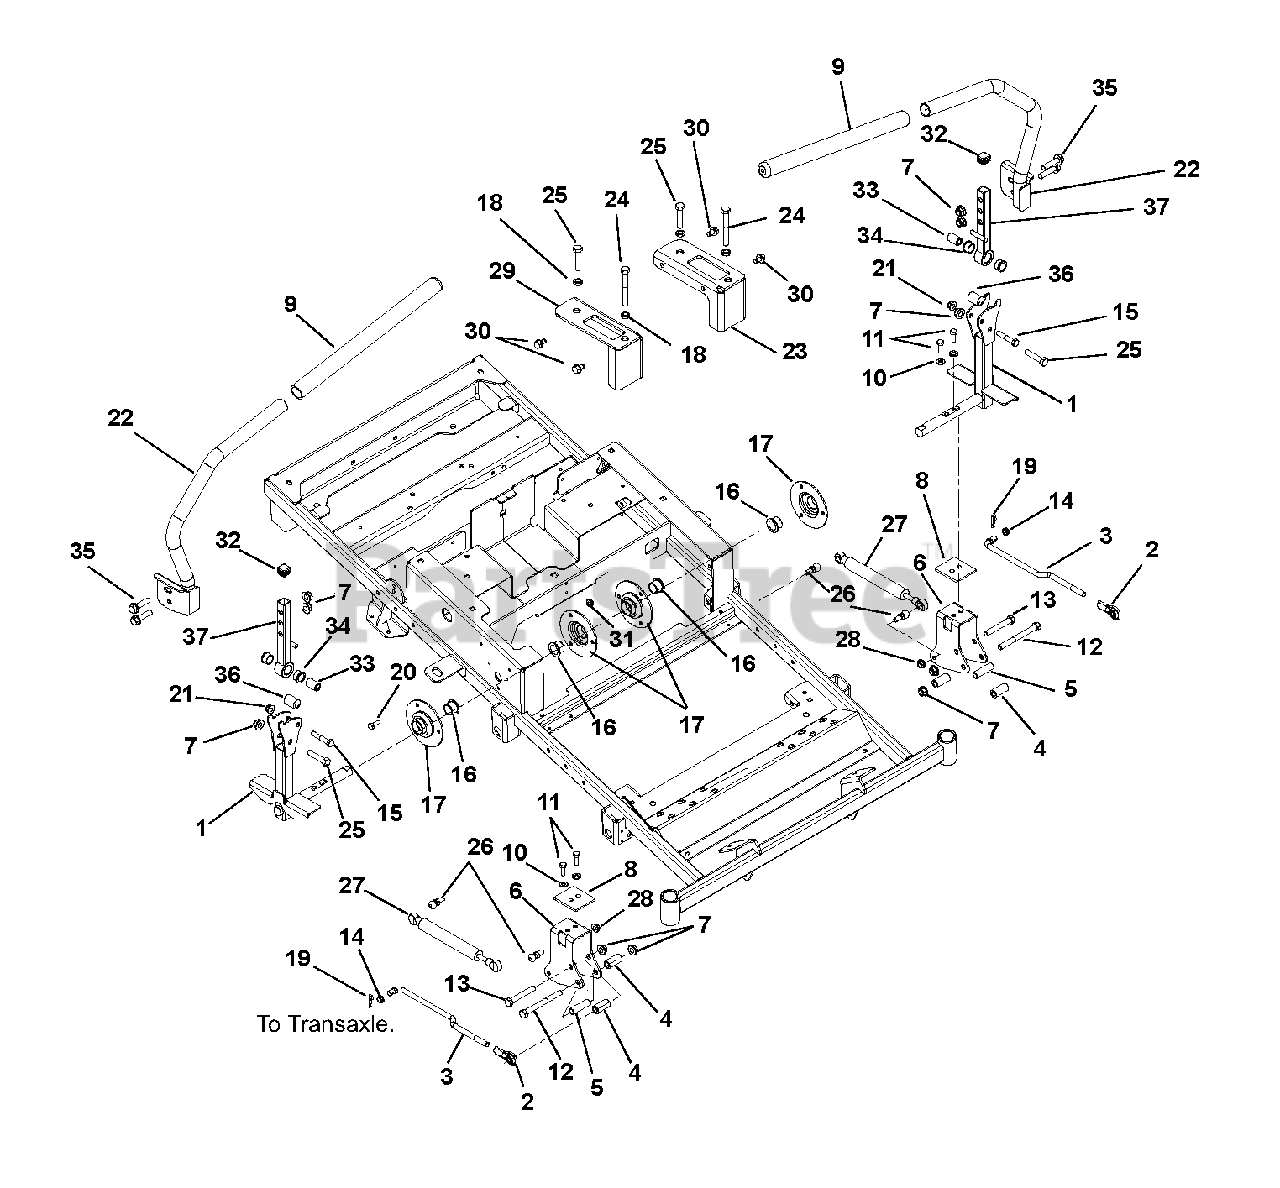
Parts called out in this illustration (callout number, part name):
1	WMT, CONTROL ARM
2	ROD END, .38 RH
3	LINK, TRANSMISSION
4	BSHG, SPCR .390X.625X1.25 PM
5	SPACER, STEERING
6	BRKT, STEERING
7	@NUT-LK-NYL-FLG .38-16 YWZC
8	PLATE, STEERING REINFORCING
9	GRIP, HANDLEBAR 15" FOAM
10	@WSHR-LK .31X.078 REG YWZC
11	BLT-HEX .31-18X1.00 GR8 YWZC
12	@BLT-HEX .38-16X3.75 GR5 YWZC
13	@BLT-HEX .38-16X2.50 GR5 YWZC
14	BUSHING, POLYLINER-.38 SNAPIN
15	@BLT-HEX .31-18X1.75 GR5 YWZC
16	BSHG-FLG .750X1.000X.625X1.250
17	BEARING FLANGE
18	NUT-HEX-JAM .375-16 YWZC
19	PIN-HAIR INT .08X.18X1.18 YWZC
20	@BLT-HEX .25-20X.75 GR5 YWZC
21	@NUT-LK-NYL-FLG .31-18 YWZC
22	WMT, STEERING HANDLE RH
23	BRACKET, LH SPEED CONTROL
24	BLT-HEX .38-16X3.00 GR5 FTH YZ
25	BLT-HEX .375-16X1.750 FTD YWZC
26	STUD- BALL
27	DAMPER, CONTROL
28	@NUT-LK-TOP-FLG .31-18 YWZC
29	BRACKET, RH SPEED CONTROL
30	@SCR-TAP .31-18X.50 HWH TR YWZ
31	@NUT-LK-TOP-FLG .25-20 YWZC
32	CAP PLUG, SQ 3/4-14-20 RIBBED
33	SPACER, .375X.625X.970 (PM)
34	BSHG-FLG, .625X.75X.450X.875
35	BOLT, SERRATED HEAD .38-16X1.5
36	BSHG, ECCENTRIC .328X.750X.970
37	WMT, UPPER CONTROL ARM
